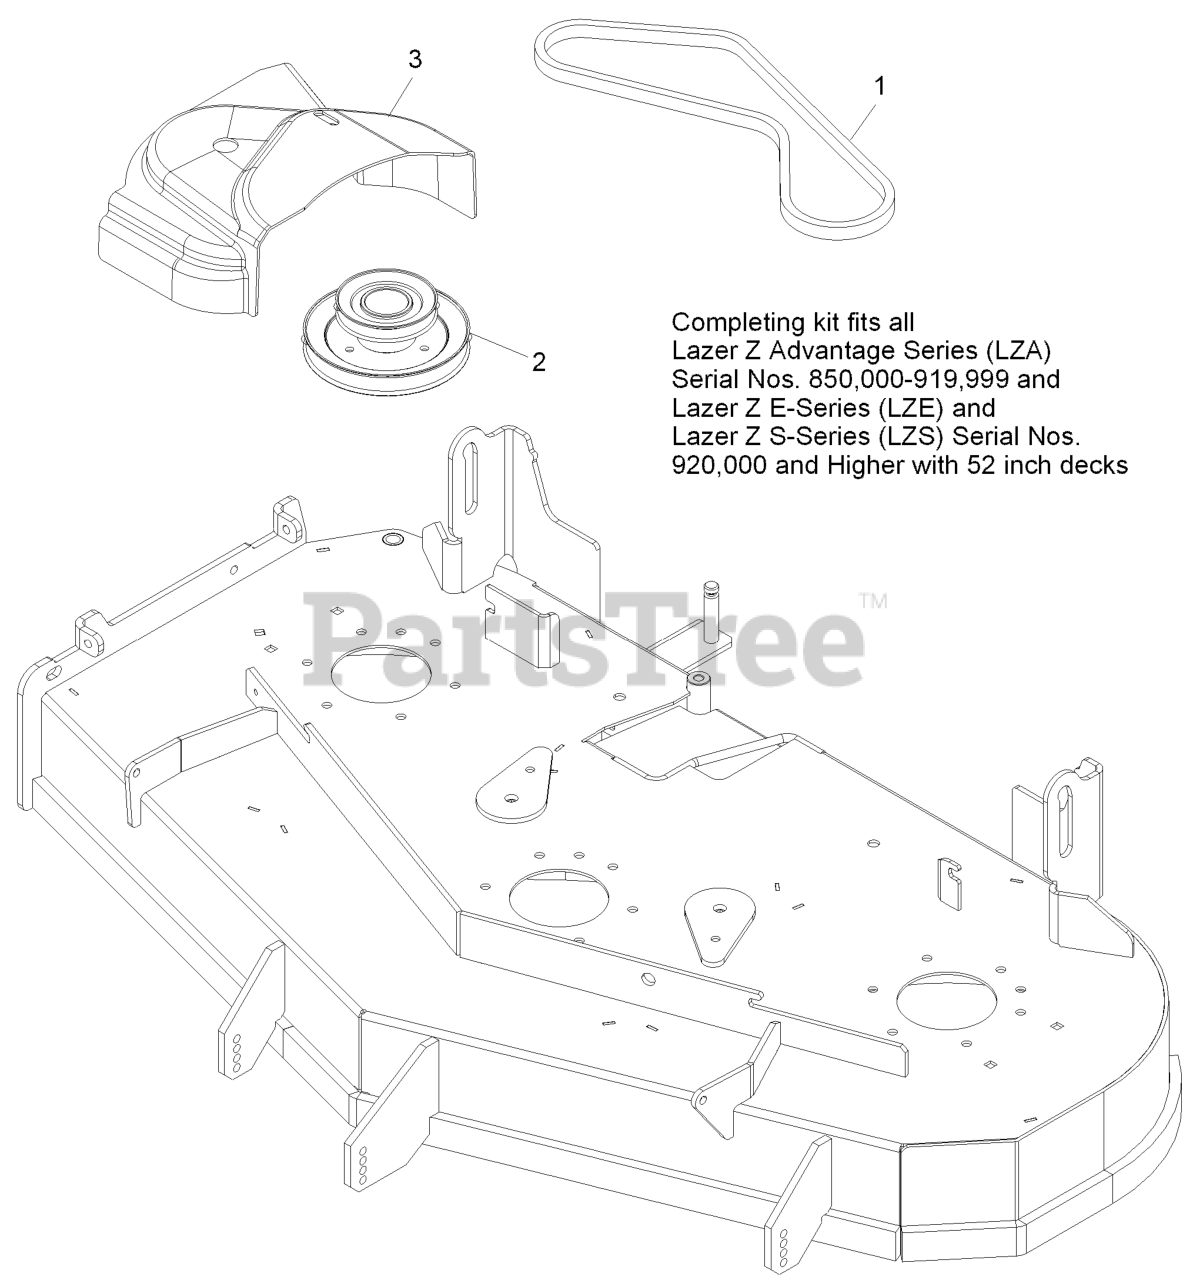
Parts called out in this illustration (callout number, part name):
1	BELT, BLOWER 52"DECK
2	JACKSHAFT,UV DRIVE 524 SP
3	COVER,BELT UV 52
